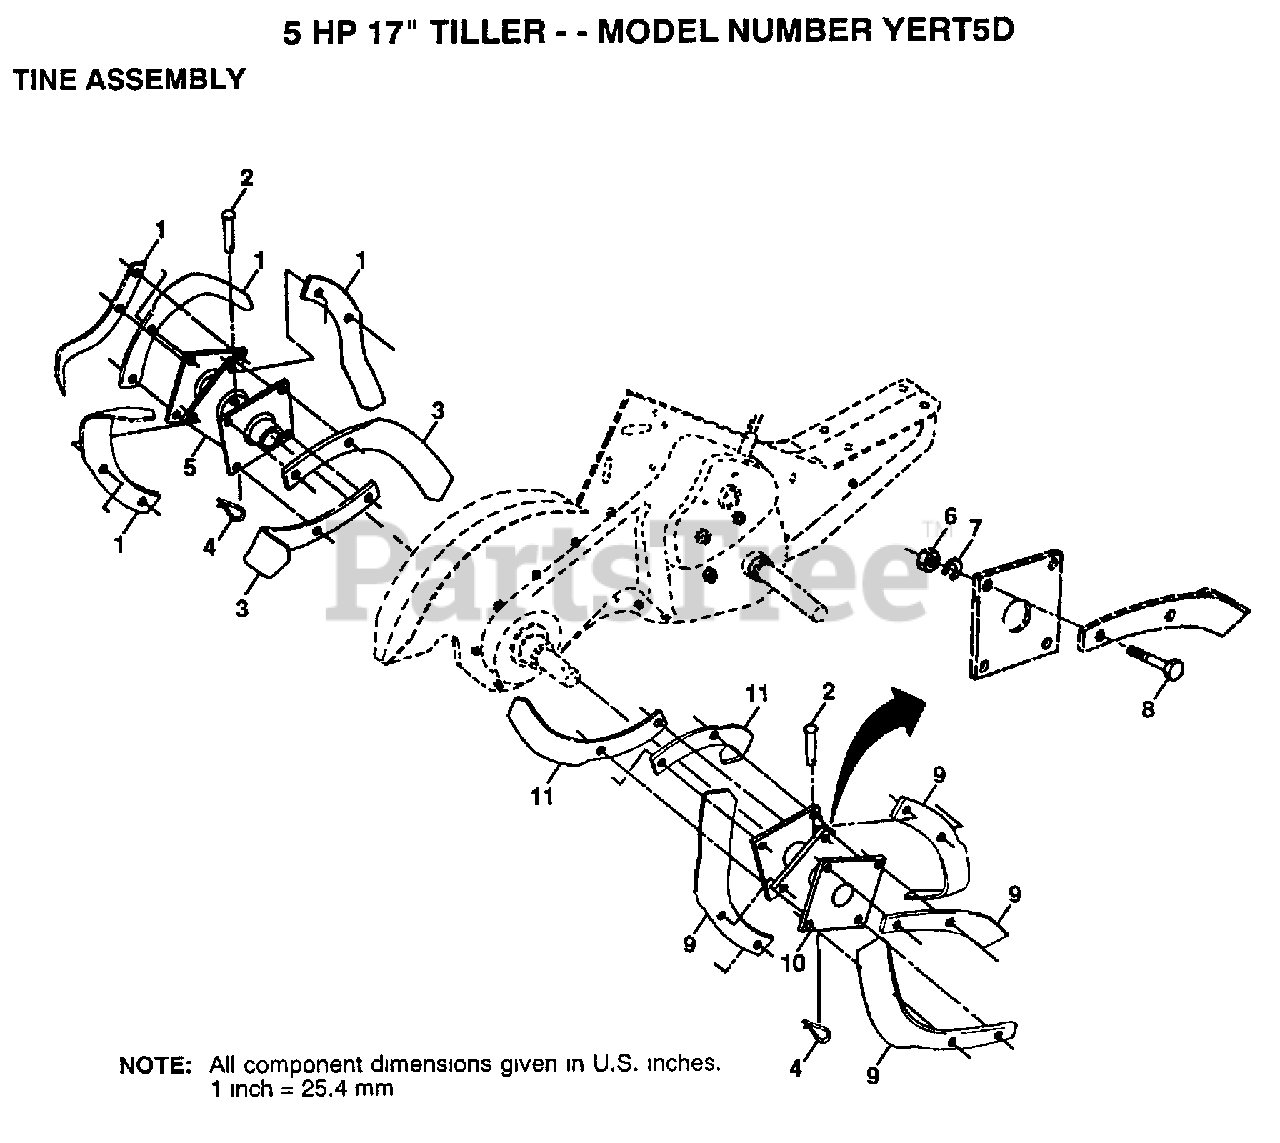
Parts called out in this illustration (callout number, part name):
2	PIN.CLEVIS.SHEAR
3	"TINE.LH.12"""
4	RETAINER.SPRING
5	HUB&PLATE ASM LH
7	LOCKWASHER
8	BOLT
10	HUB&PLATE ASM RH
11	"TINE.RH.12"""
